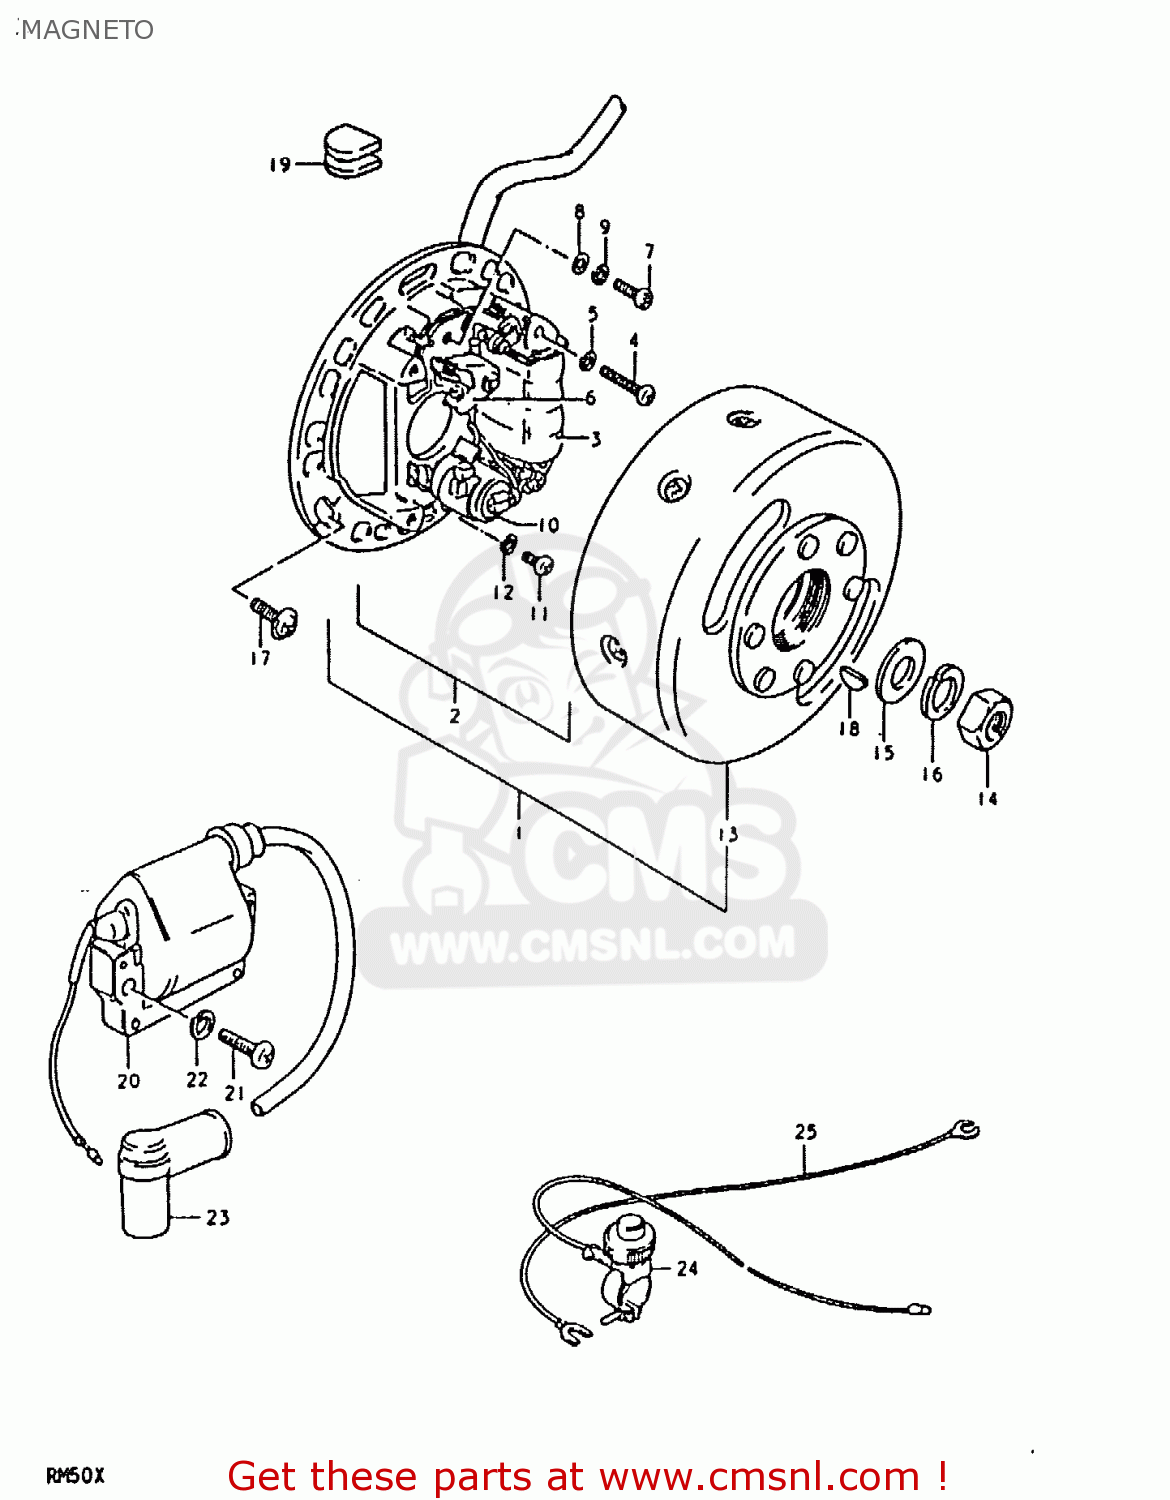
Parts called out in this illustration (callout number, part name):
1	MAGNETO ASSEMBLY
2	STATOR ASSEMBLY
3	COIL,PRIMARY
4	SCREW (4X30)
5	LOCK WASHER
6	POINT ASSY,CONTACT
7	SCREW(4X10)
8	WASHER
9	LOCK WASHER
10	CONDENSER
11	SCREW
12	LOCK WASHER
13	ROTOR ASSEMBLY
14	NUT (10MM)
15	WASHER
16	LOCK WASHER
17	SCREW(5X14)
18	KEY
19	PLUG
20	COIL ASSEMBLY,IGNITION
21	SCREW
22	LOCK WASHER
23	CAP,SPARK PLUG
24	SWITCH ASSEMBLY
25	WIRE,ENGINE STOP EARTH
